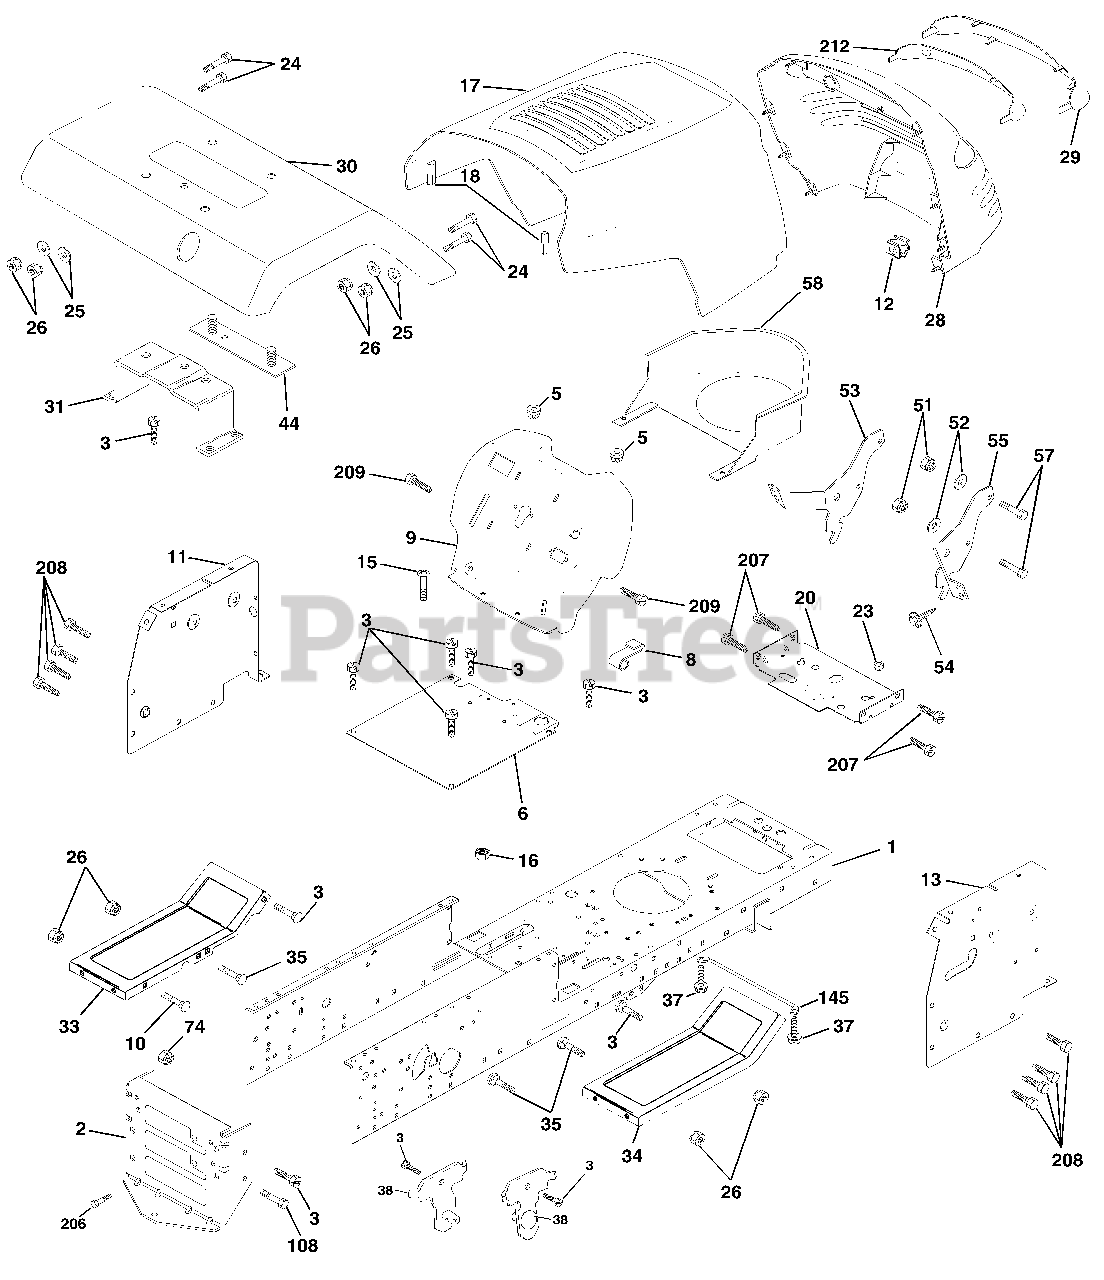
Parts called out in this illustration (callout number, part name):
1	Chassis Wldmt.
2	Drawbar Stretch 94
3	Screw 3/8-16 x 3/4
4	Washer 13/32 x 3/4 x 16 Ga.
5	Bumper Hood/Dash
6	Saddle Flat Lt
8	Clip Retainer Slide-On
9	Dash Private Label
10	Bolt Rd Hd Sqnk. 3/8-16 Unc x 1
11	Panel Asm. Dash Lh
12	Clip Tinnerman Grile P/L
13	Panel Dash Rh
15	Screw Mach Trhd 5/16-18 Unc x 3/4
16	Nut Keps 5/16-18 Unc
17	Hood Pnt STL P/L w/trim
18	Bumper Hood
20	Plate Mtg Battery/Fule Tank
23	Bushing Snap Nyl Blk Fuel Line
24	Bolt Fin Hex 3/8-16 Unc x 1 Gr. 5
25	Washer 13/32 x 13/16 x 12 Ga.
26	Nut Lock Hex w/Insert 3/8-16 UNC
28	Grill Private Lable Blk
29	Lens Grille Private label
30	Fender Asm YTGT
31	Bracket Fender
33	Footrest Pnt. Lh
34	Footrest Pnt. Rh
35	Bolt Rd Hd Sht. Sqnk. 3/8-16 x 3/4
37	Screw Thdrol 5/16-18 x 1/2 Tyt
38	Bracket Asm Pivot Mower Rear
44	Strap Asm Fender
51	Nut Lock Hex W/Ins. 1/4-20
52	Washer 9/32 x 7/8 x 16 Ga.
53	Bracket Grille LH
54	Screw Hex Wshd 8-18 x 7/8
55	Bracket, Grille RH
57	Bolt Fin Hex 1/4-20 x .75
58	Air Duct Private Label
74	Nut Crownlock 3/8-16 Unc
108	Bolt Fin Hex 3/8-16 Unc x 3/4
145	Rod Pivot Chassis/Hood
206	Bolt Shoulder 5/16-18
207	Screw Thdrol 5/16-18 x 1/2
208	Screw Thdrol 3/8-16 x 1/2
209	Screw Hex wsh Thdrol 3/8-16 x 3/4
